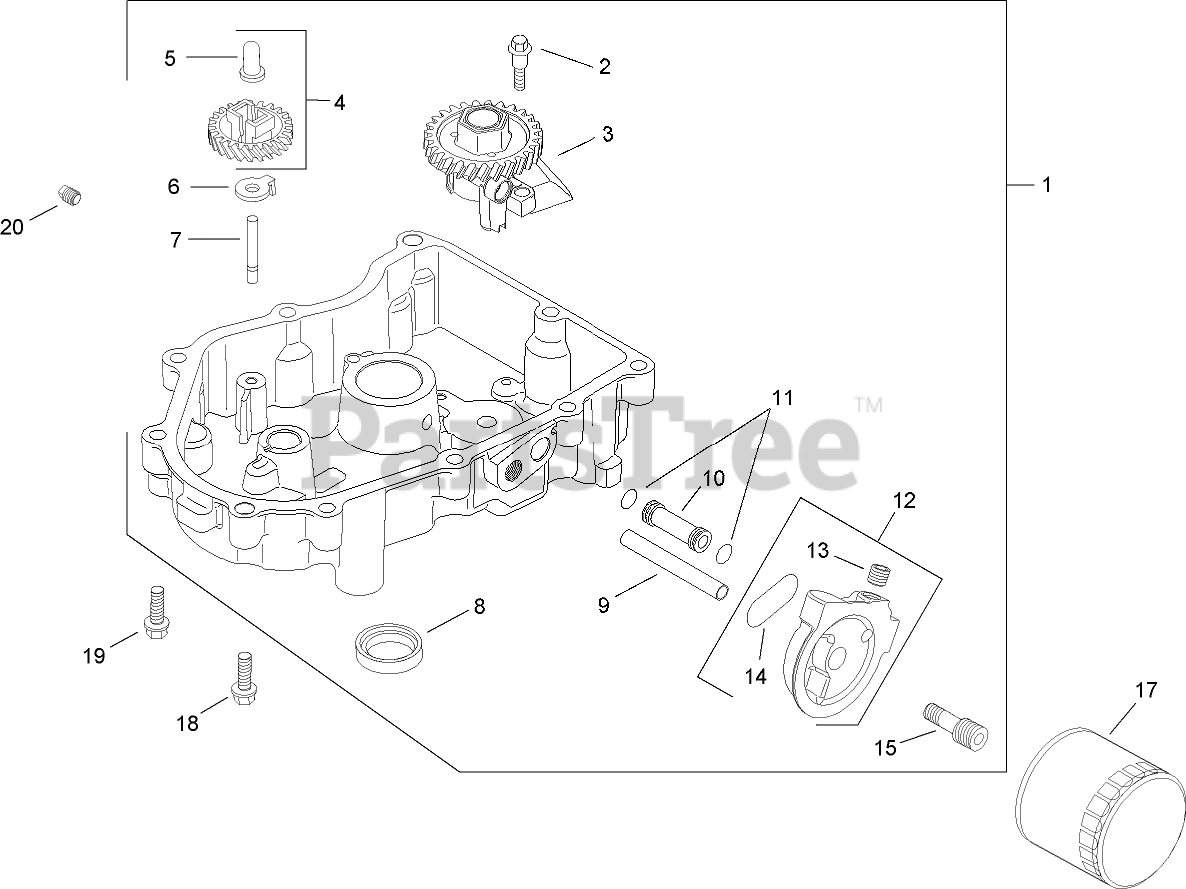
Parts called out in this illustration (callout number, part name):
1	Oil Pan ASM (Includes2-15)
2	Screw-Hex Flange, Thread Forming (Shoulder)
3	Oil Pump ASM
4	Governor Gear Kit w/Pin (Includes5)
5	Pin-Governor Regulating
6	Tab-Locking
7	Shaft-Governor Gear
8	Seal-Oil (PTO end)
9	Tube (Oil feed filter to oil pan)
10	Tube (Oil feed oil pan to filter)
11	O Ring
12	Adapter-Oil Filter (Includes13-14)
13	Plug-Hex, Countersunk (1/8)
14	O Ring-Oil Filter Adapter
15	Nipple-Oil Filter
17	Filter-Oil
18	Screw-Hex Flange (M8x1.25x45)
19	Screw-Hex Flange (M8x1.25x45)
20	Plug-Square Head, Solid (3/8)
